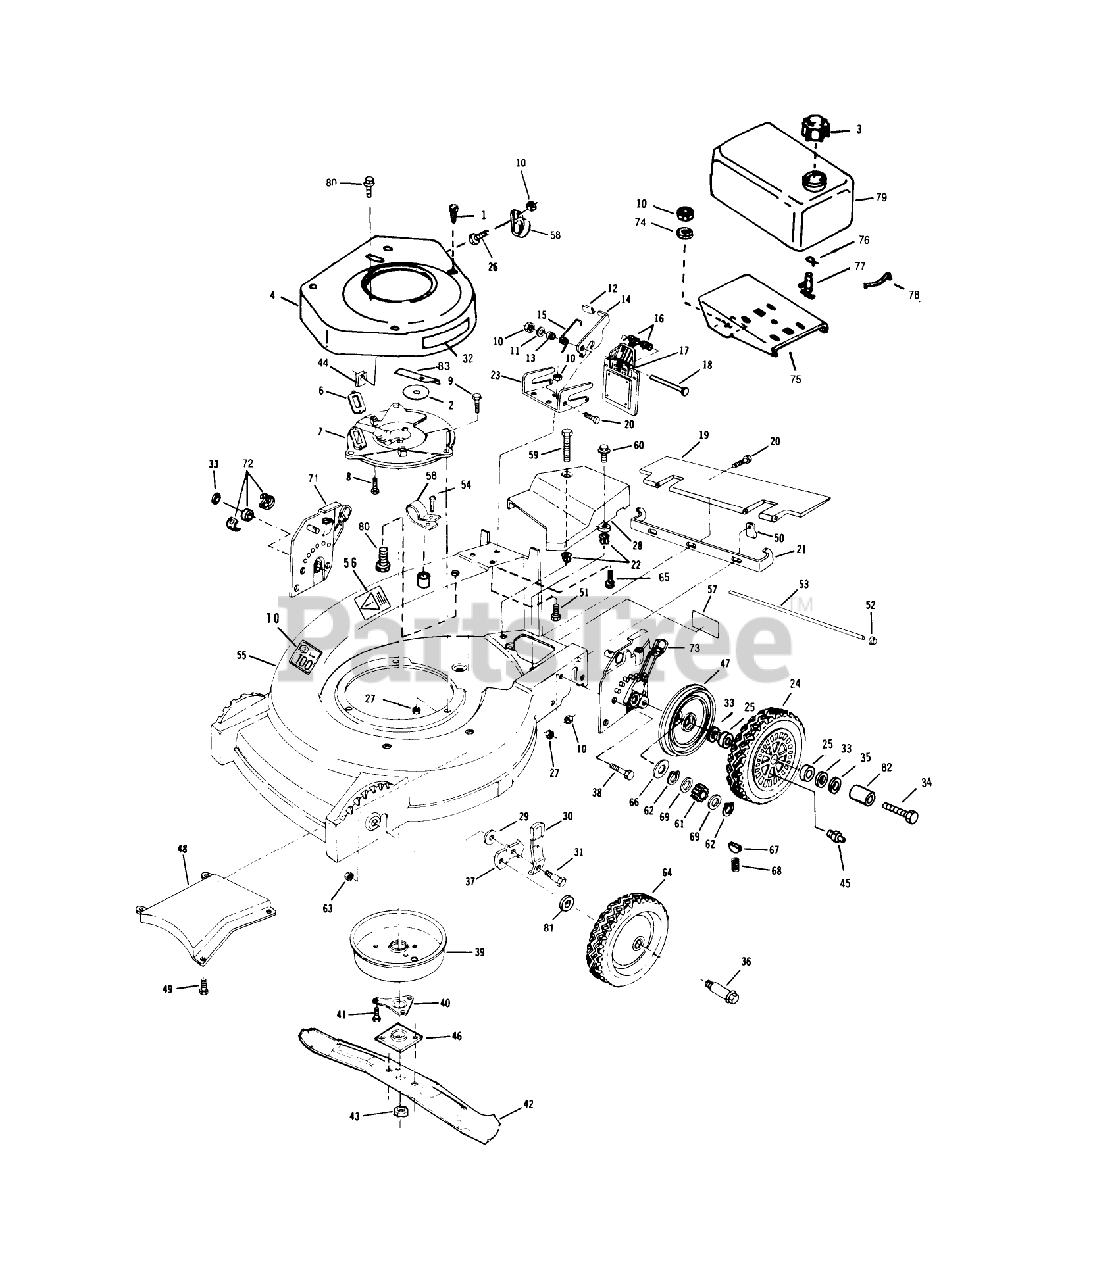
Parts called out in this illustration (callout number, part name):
1	SCREW - SELF TAPPING
3	FUEL CAP & INSERT
8	SCREW V
9	SCREW-HH
10	LOCKNUT E
12	KNOB (S&R)
15	SPRING
16	SPRING ASOC
18	ROD (RB&W)
19	T/SHIELD SM&P
27	NUT-LOCK F
29	WASHER
30	SPRING ARM ASM
31	BOLT
33	WASHER
35	SPACER
36	BOLT-SHOULDER
39	MUFFLER COVER F
40	SUPPORT F
41	SCREW
43	NUT-BLADE
44	PUSHNUT F
45	FITTING LINCOLN
46	PLATE AND COLLAR ASM
48	BAFFLE CHUTE PL
51	SCREW
54	SCREW LAWRENCE
60	SCREW
61	PINION BROCKWAY
62	RET RING
63	LOCKNUT
65	SCREW HEX WASHER
66	THRUST WASHER
67	KEY
68	SPRING
69	SPACER/GR ALGHNY
72	REAR AXLE BEARING
74	WASHER
75	BRACKET - TANK
76	CLAMP - HOSE S
77	VALVE&SCREEN SM
78	SPRING
80	SCREW SEMS SM
81	WASHER WROUGHT
